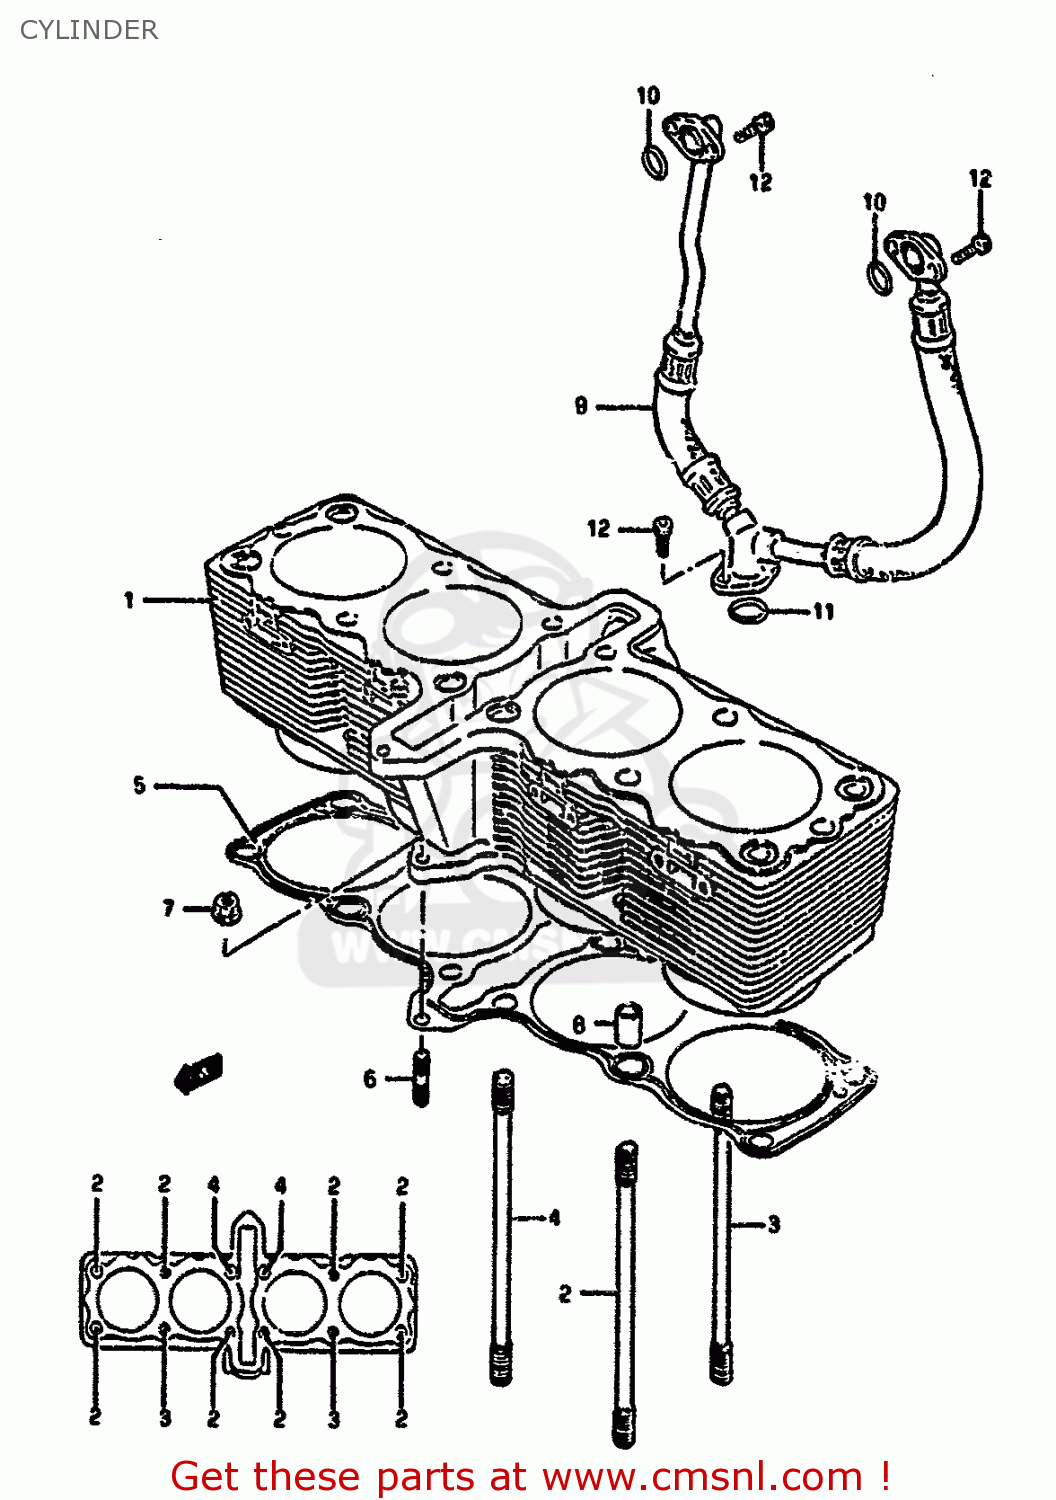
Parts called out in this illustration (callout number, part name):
1	CYLINDER
2	BOLT,STUD
3	BOLT,STUD
4	BOLT,STUD
5	GASKET,CYLINDER (NAS)
6	STUD BOLT L:20
7	NUT
8	PIN
9	HOSE
10	O RING(D:2.5,ID:13.8)
11	O RING(D:2.4,ID:15.8)
12	BOLT
